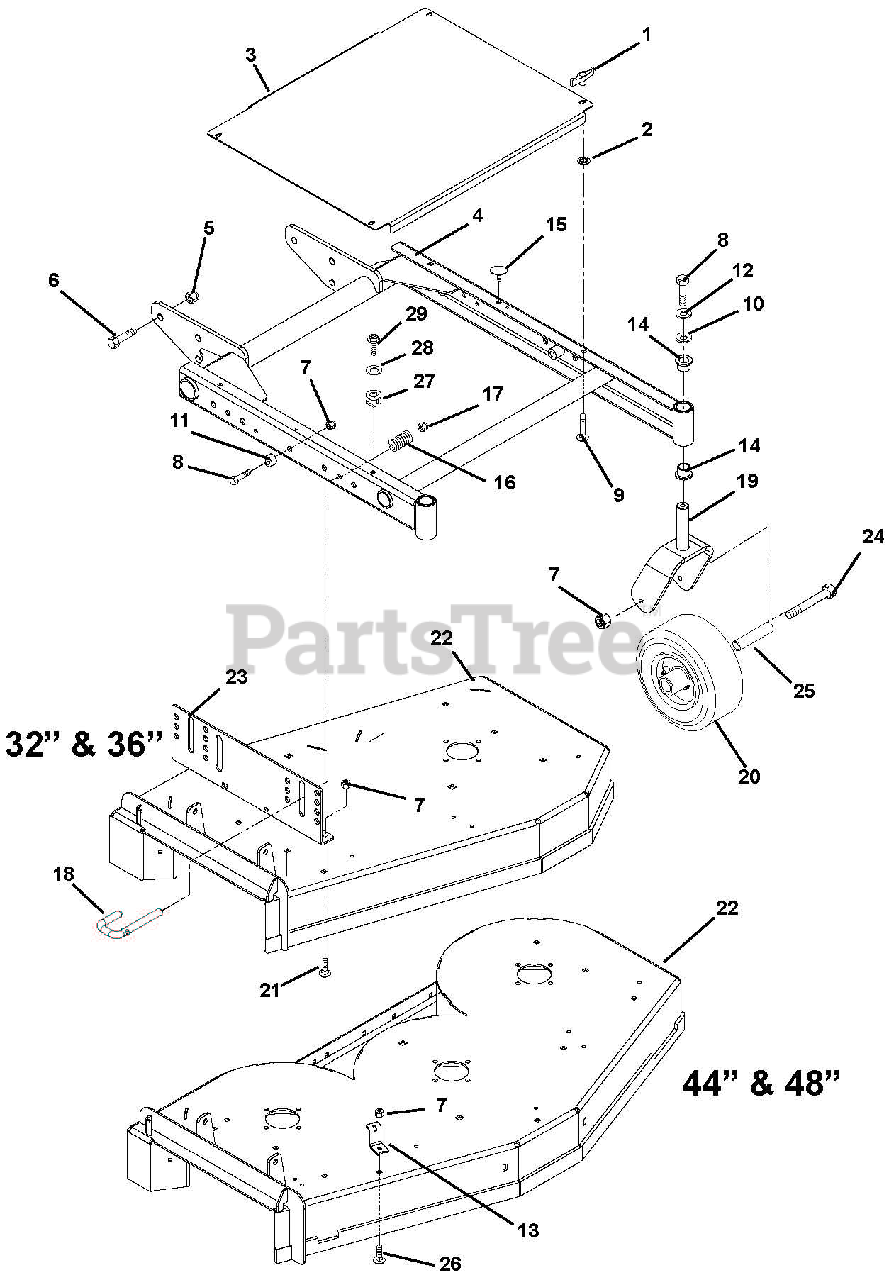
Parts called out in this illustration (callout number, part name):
1	Knob- Wing .312-18
2	Nut-Push .312
3	Cover, Belt Pro Mower
3	Cover- Belt- Pro- 32
3	Cover- Belt- Pro- 44
4	Weldment - Mower Frame 36"
4	Weldment - Mower Frame 48"
4	Weldment - Mower Frame 44"
4	Weldment - Mower Frame 32"
5	Nut-Locking-Nylon .625-11
6	Bolt-Hex .62-11 x 1.50
7	Nut-Locking-Top-Flange .38-16
8	Bolt-Hex .38-16 x 1.25 Grade 5
9	Bolt-Round Head Square Neck .31-18 x 1.00
10	Washer-Flat-Steel .38 x 1.50 x .125
12	Washer-Locking .38 x .094 Regular
13	Anchor, Spring
14	Bushing-Flange 1.00 x 1.25 x 1.50 x 1.50
15	Bumper Grommet .125 x .25 Dia.
16	Spring-Compression .058 x .65 x 2.13
17	Nut-Locking-Center .50-13
18	Pin- Latch
19	Weldment-Caster Fork
20	Wheel 9 x 3.50
21	Bolt-Round Head Square Neck .38-16 x 1.00 Grade 5
22	Kit, 36" Fixed Mower Deck with Decals
22	Kit, 48" Fixed Mower Deck with Decals
22	Kit, 44" Fixed Mower Deck with Decals
22	Kit, 32" Fixed Mower Deck with Decals
23	Kit-Mower Side Support Bracket-Right Hand and Left Hand
24	Bolt-Hex .38-16 x 5.50
25	Bearing .625 x .380 x 4.08
26	Bolt-Round Head Square Neck .38-16 x .75 Grade 5
27	Grommet, Plastic
28	Washer-Flat-Steel .281 x .62 x .065
29	Screw-Tapping .25-20 x .50 Hex Washer Head
